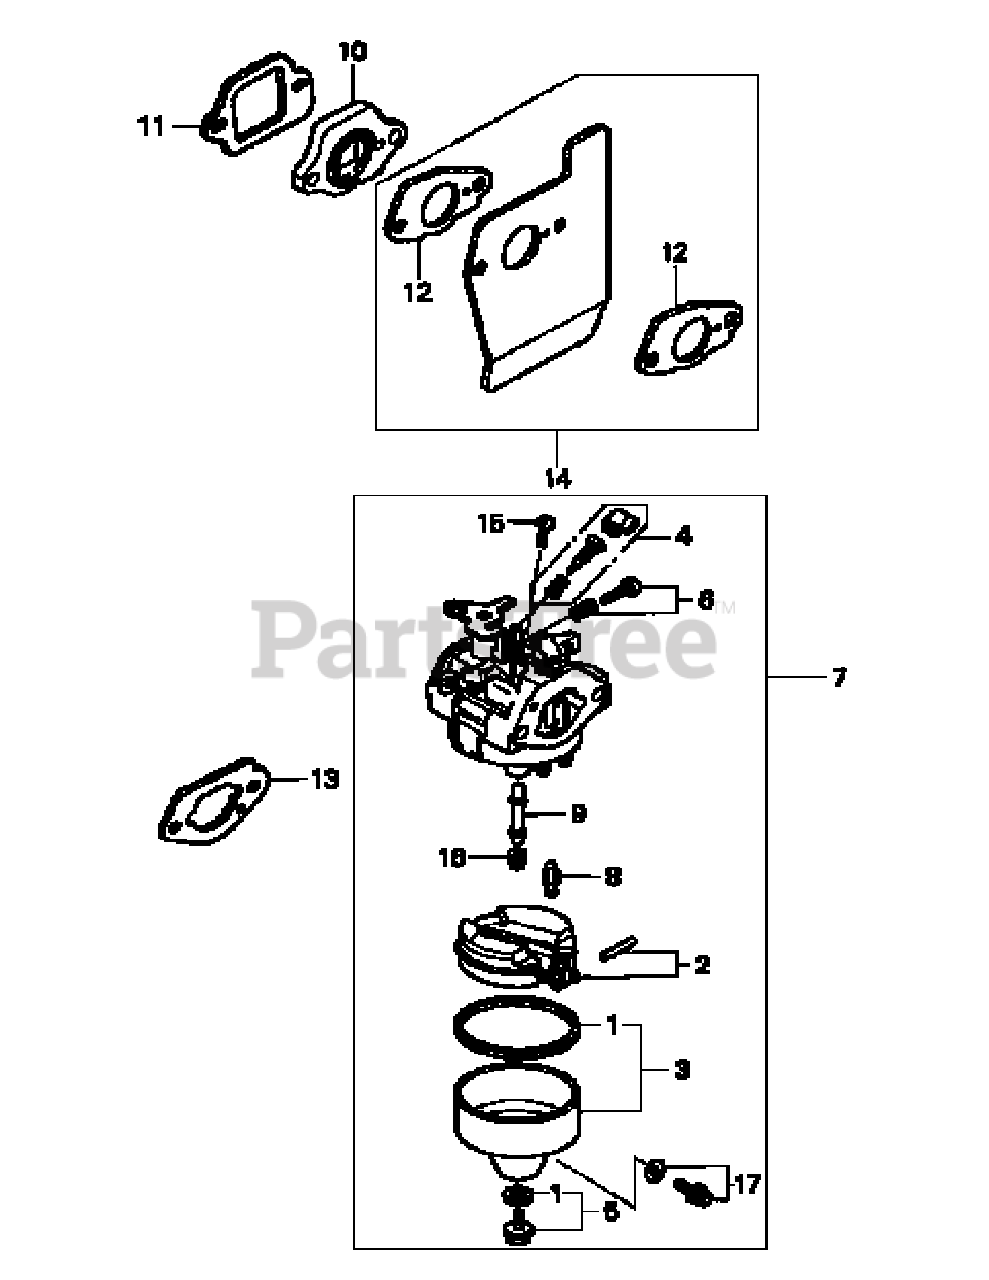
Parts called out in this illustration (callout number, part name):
1	Gasket Set
3	Float Chamber Set
5	Screw Set
7	Carburetor Assy.
8	Float Valve
9	Main Nozzle
10	Carburetor Insulator
11	Insulator Gasket
12	Carburetor Gasket
13	Carburetor Gasket
16	Main Jet (#60)
17	Drain Set Screw
